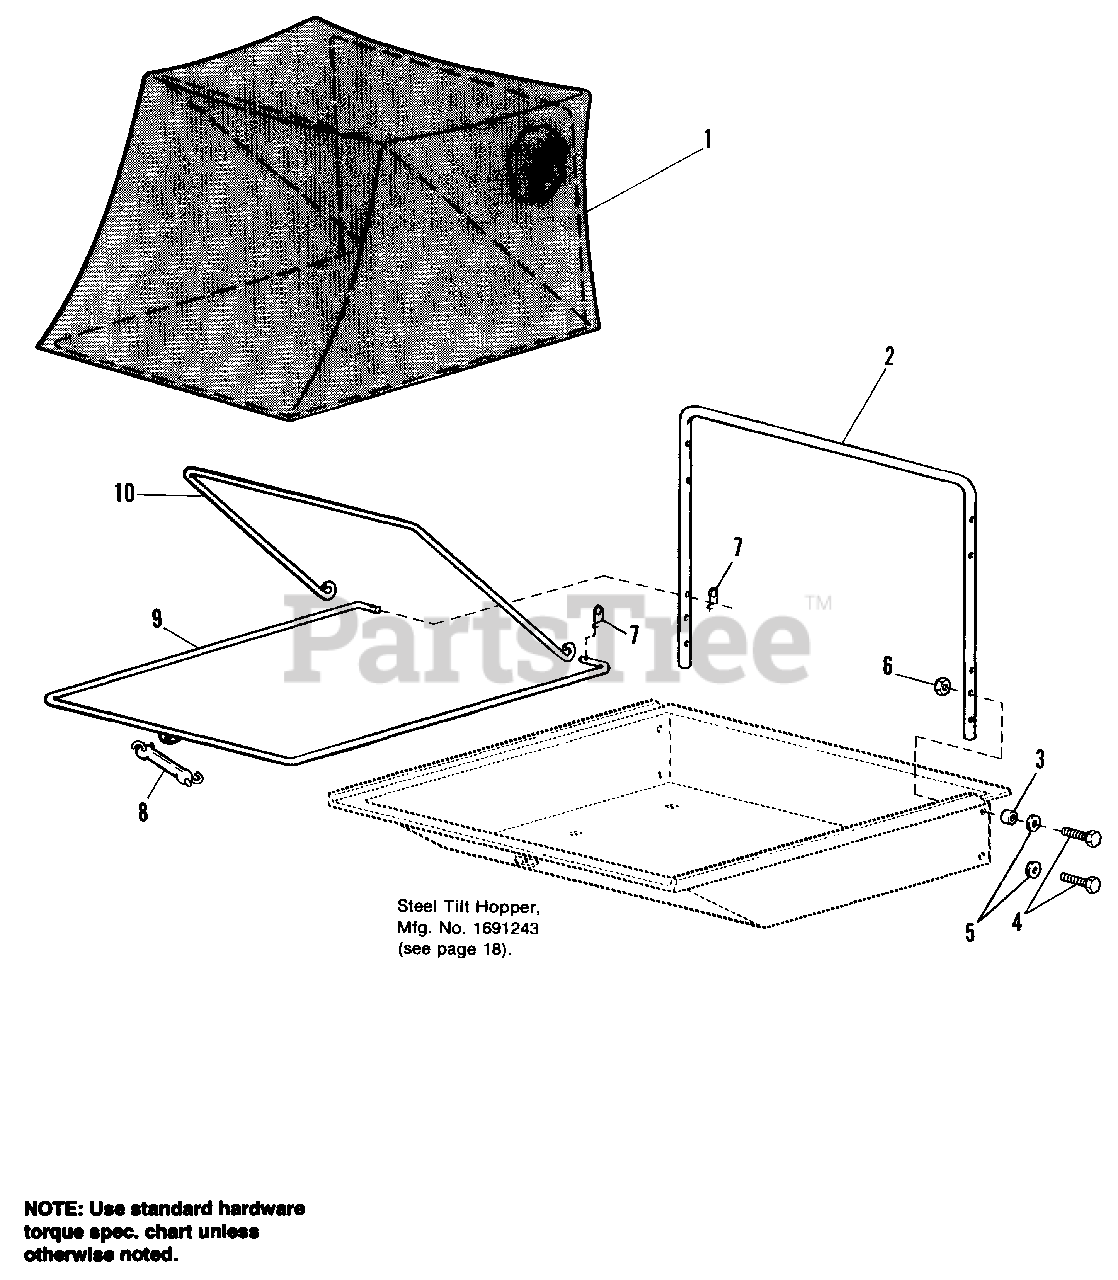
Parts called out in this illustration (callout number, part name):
2	TUBE, Support
3	SPACER, Plastic
4	CAPSCREW, 5/16-18 x 1-1/2
5	WASHER, Lock, 5/16-18
6	NUT, Lock, 5/16-18
7	COTTER, Hairpin
8	STRAP, Rubber
9	ROD, Frame
10	ROD, Support
